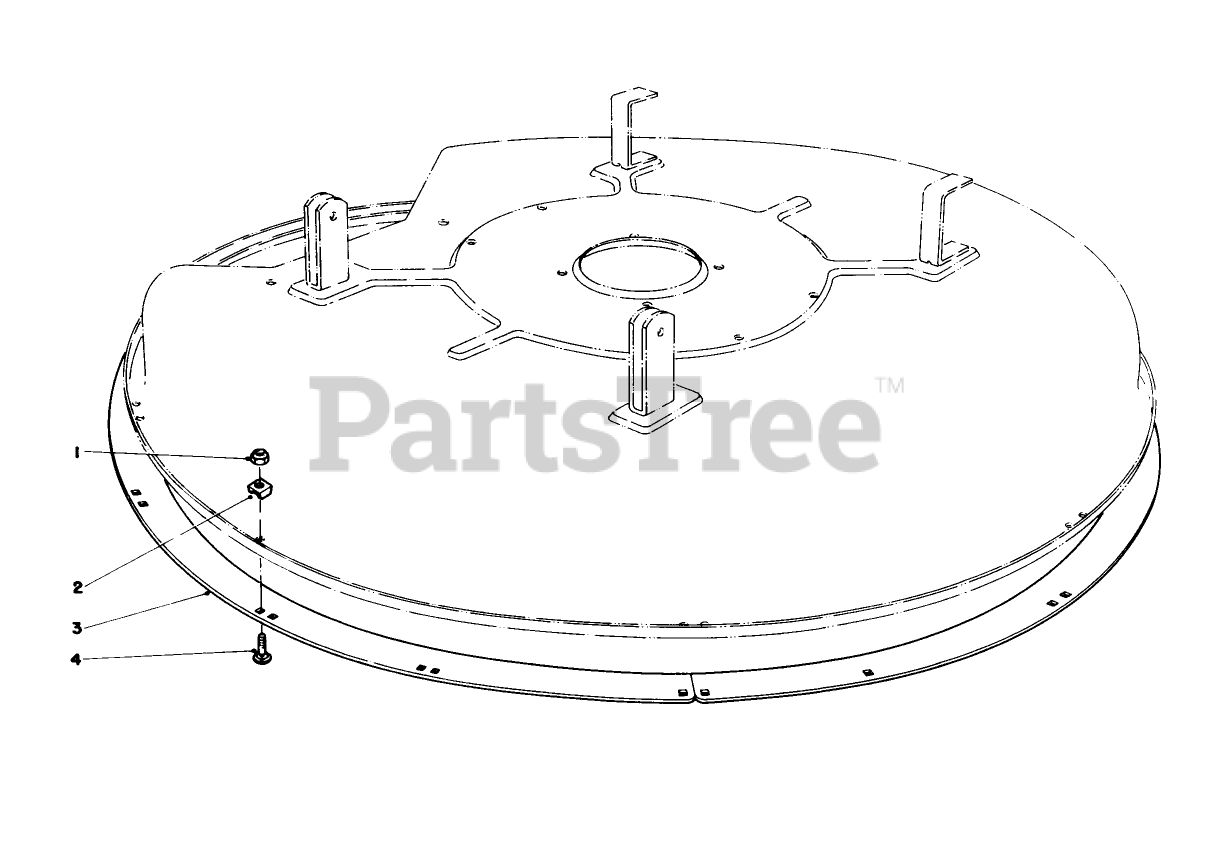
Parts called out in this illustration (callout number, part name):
1	NUT-LOCK, NI
3	DECK RING *B
4	BOLT-CARR
